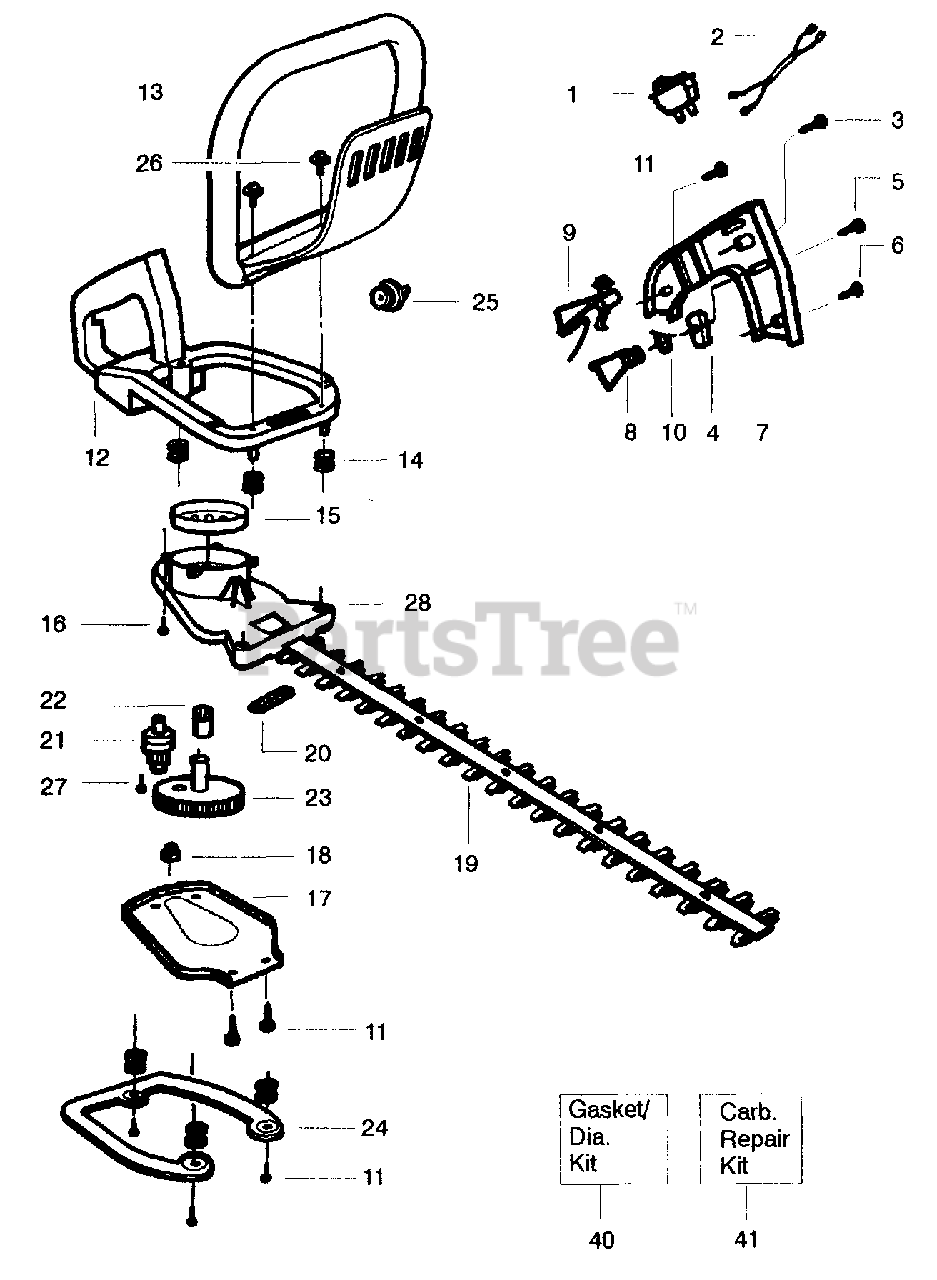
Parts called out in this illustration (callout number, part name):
1	Ignition Switch
2	Switch Wire Ass'y.
3	Screw-Handle Cov.
4	Trigger Lever
5	Screw-Handle Cov.
6	Screw-Handle Cov.
7	Handle Cover
8	Throttle Trigger
9	Throttle Lockout
10	Trigger Spring
11	Screw-Handle Cov.
12	Rear Handle/Tank Ass'y.
13	Front Handle
14	Isolator Spring
15	Clutch Drum
17	Gear Box Plate
18	Bushing Blade
19	Blade Ass'y.
20	Blade Seal
21	Pinion Ass'y.
22	Drive Gear Bearings
23	Drive Gear Kit
24	Isolator Plate
25	Fuel Cap Ass'y.
26	Screw-Front Handle
27	Screw-Gear
28	Gear Box Ass'y.
40	Walbro - Gasket/Diaphragm Kit
40	Zama - Gasket/Diaphragm Kit
41	Carb. Repair Kit - Type 1
41	Walbro - Carb. Repair Kit - Type 2
41	Zama - Carb. Repair Kit - Type 2
